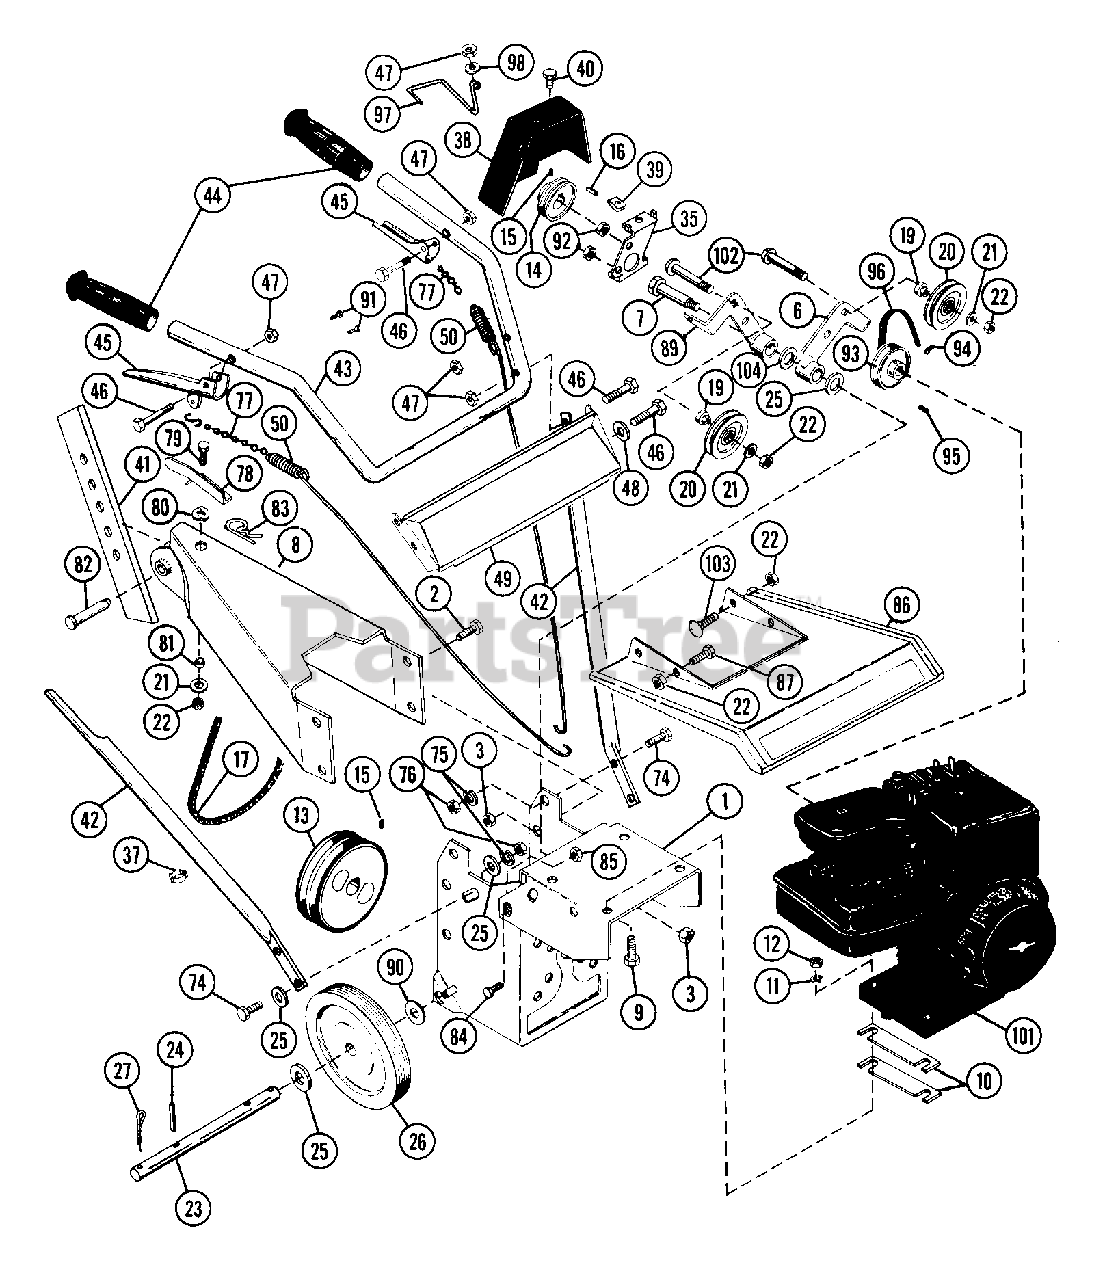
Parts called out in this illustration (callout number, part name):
1	FRAME
2	BLT-HEX .38-16X.75 PL GR2
3	NUT-LK-CTR .375-16 GR A PL
6	IDLER ARM FWD
7	WHEEL SHOULDER BOLT
8	DEPTH STICK HOLDER
9	BLT-HEX .31-18X1.75 PL GR2
10	SHIM
11	WSHR-LK .312X.097 PL HVY
12	NUT-HEX .312-18
13	PLY-DBLV 5.50 X.75 W/KEY SALEM
14	ENGINE SHEAVE
15	SET SCREW
16	KEY-SQ .188X1.0X.188 SAE 8630
17	V-BELT, 4L-WRAPPED
18	BLT-HEX .38-16X1.25 PL GR 2
19	SPCR, BRG .315X.50X.688X.281
20	IDLER
21	WSHR-FL-STL .38X.875X.083 PL
22	NUT-LK .312-18 GR A PL
23	AXLE ROD
24	PIN-ROLL .125X1.38
25	WSHR-FL-STL .531X1.062X.095 PL
27	PIN-COTR .12 X 1.25 PL
35	BELT GUARD BRACKET
38	BELT COVER
39	NUT-SPEED U-TYPE .250-20
40	BLT-HEX .25-20X.50 PL GR2
41	DEPTH STICK
42	LOWER HANDLE BAR
43	HANDLEBAR
44	GRIP
45	CLUTCH HANDLE
46	BLT-HEX .25-20X1.50 PL GR5
47	NUT-LK-CTR .250-20 PL
48	WSHR-FL-STL .268X.562X.046 PL
49	HANDLEBAR PANEL
50	SG-TENS .080X.25X31.6 WLD 35
74	BLT-HEX .38-16X1.00 PL
75	WSHR-LK .375X.115 HVY PL
76	NUT-HEX .375-16
77	CLUTCH CHAIN
78	RETAINER CLIP
79	BLT-HEX .31-18X.75 PL GR2
80	WAVE WASHER .515 X 1.00 X .125
81	SPACER BUSHING .5 X .32 X .21
82	CLEVIS PIN .437/.431X1.50 YWZC
83	PIN-HAIR INT .12X2.75
84	BLT-HEX .38-16X.75 PL GR5
85	NUT-LK TOP .375-16 GR C YWZC
86	TINE HOOD
87	BLT-HEX .31-18X.63 PL GR 2
89	IDLER ARM REV.
90	SPACER .76 X .51 X .56
91	SCR-TAP 10-12X.50 CRPH PL A
92	NUT-LK-FLG .250-20 PL
93	REVERSE SHEAVE
94	SCR-SET .25-20X.25 SKHCUPNY OH
95	KEY-WDRF .125X.625X.250 SAE5
96	V-BELT, 3L-WRAPPED
97	BELT FINGER
98	WSHR-FL-STL.281X.62X.065 PL
102	BLT-RDHDSQNK .31-18X1.25 SHTPL
103	BLT-RDHDSQSHNK .31-18X.50 YZ
104	WSHR-FL-STL .520X.827X.062 YZ
